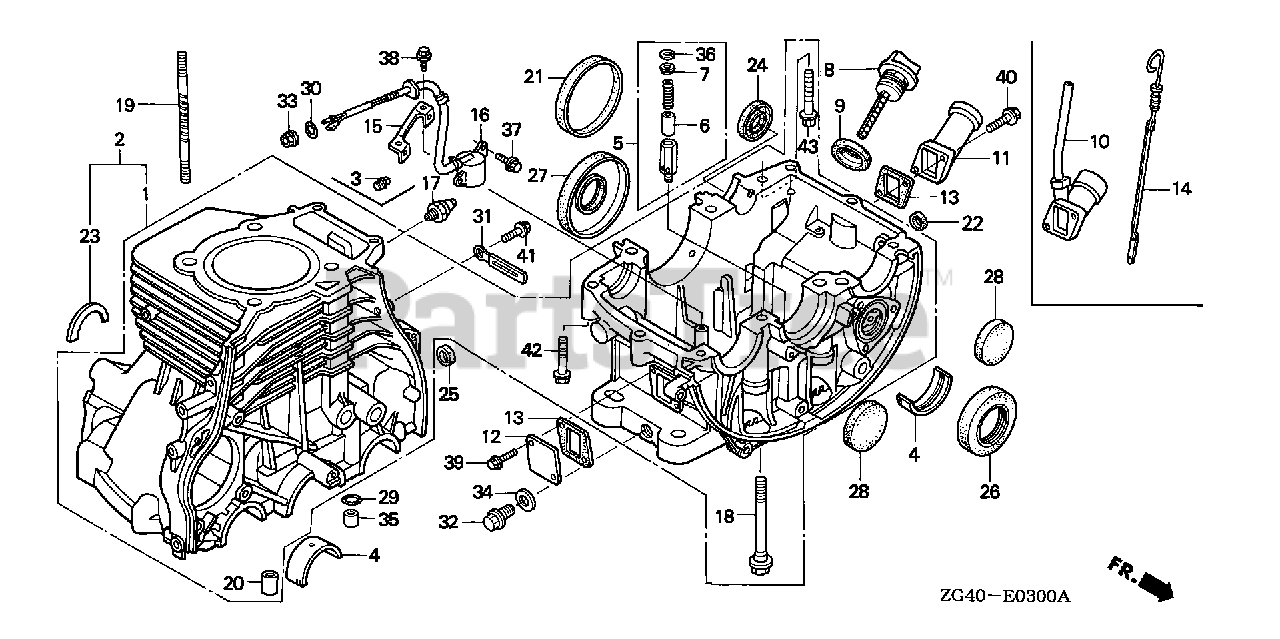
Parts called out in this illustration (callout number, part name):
1	CYLINDER ASSY.
4	BEARING A, MAIN (BLUE)
4	BEARING B, MAIN (BLACK)
4	BEARING C, MAIN (BROWN)
4	BEARING D, MAIN (GREEN)
4	BEARING E, MAIN (YELLOW)
4	BEARING F, MAIN (PINK)
4	BEARING G, MAIN (RED)
4	BEARING A, MAIN
4	BEARING B, MAIN
4	BEARING C, MAIN
5	VALVE ASSY., RELIEF
6	VALVE, RELIEF
7	SEAT, RELIEF VALVE
8	CAP, OIL FILLER
9	GASKET, OIL FILLER CAP
11	EXTENSION, OIL FILLER
12	PLATE, EXTENSION
13	GASKET, EXTENSION OIL FILLER (NON-ASBESTOS)
18	BOLT-WASHER (11X115)
19	BOLT, STUD (10X103.5)
20	PIN, DOWEL (13X20)
23	SET-RING (80)
25	OIL SEAL (8X14X5)
26	OIL SEAL (37X64X10)
27	OIL SEAL (31X80X10)
28	PLUG, SEALING (47MM)
29	O-RING (9.8X1.9)
32	BOLT, DRAIN PLUG (14MM)
34	WASHER, DRAIN PLUG (14MM)
35	PIN, DOWEL (10X16)
36	CIRCLIP, INNER (12MM)
39	BOLT, FLANGE (6X16)
40	BOLT, FLANGE (6X22)
42	BOLT, FLANGE (8X40) Use up to Engine SN 1003236.
42	BOLT, FLANGE (8X40)
43	BOLT, FLANGE (8X50)
